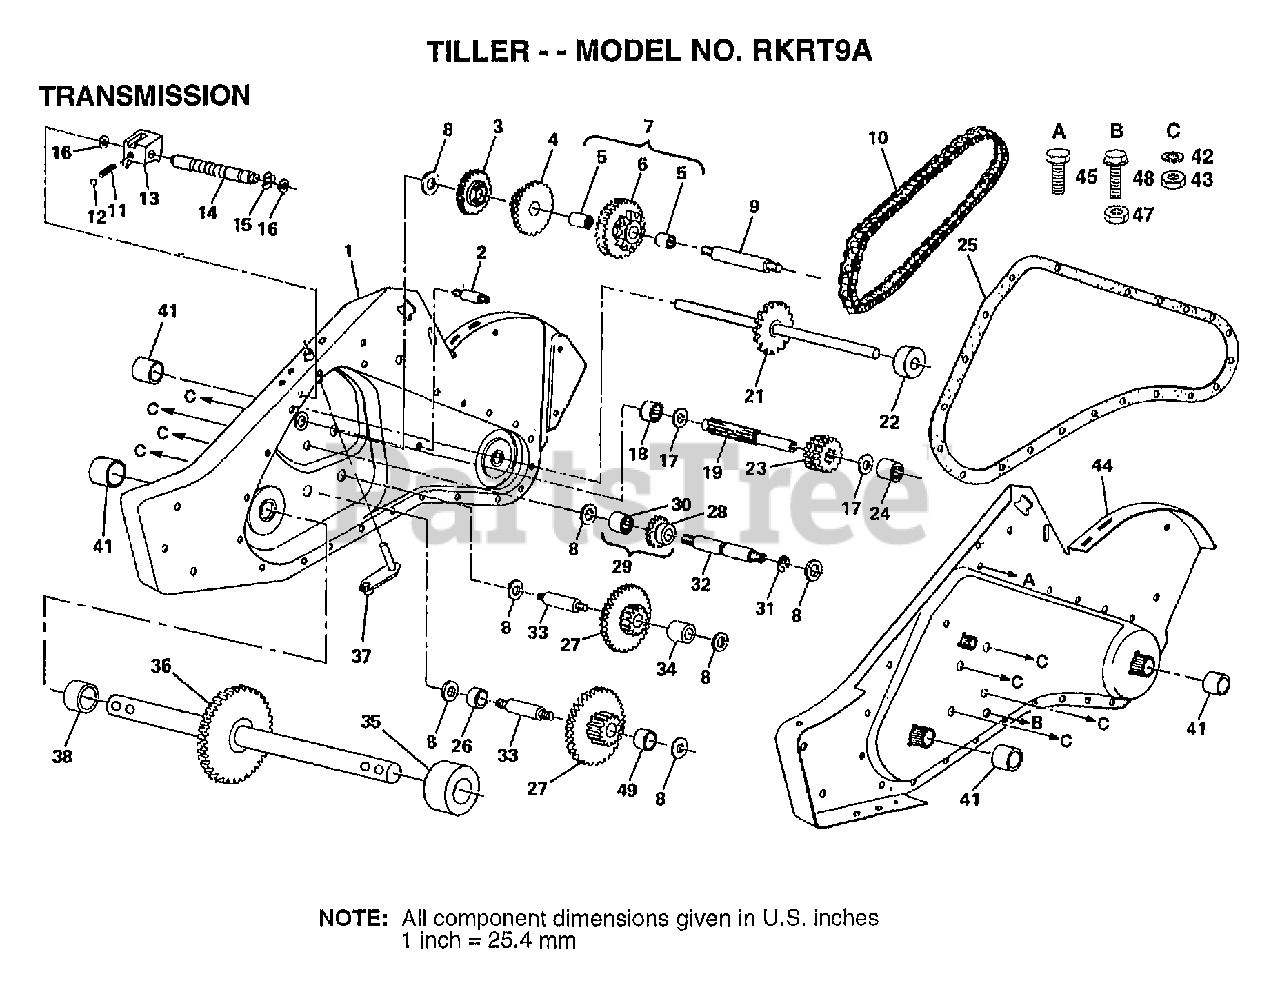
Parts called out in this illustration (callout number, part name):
2	BOLT TI
3	REVERSE GEAR TI
4	CLUSTER GEAR TI
5	"CRT, BEARING"
7	SPROCKET ASSY TI
8	WASHER
9	REDUCTION SHFT TI
10	CHAIN TI
11	SPRING-SHIFT CRT
13	SHIFT FORK TI
14	SHIFT SHAFT TI
15	KLIP RING
16	WASHER SEAL
17	"T, BEARING"
18	"TI, BEARING"
19	SHAFT INPUT
21	SHAFT TINE CRT
22	SPACER CRT
23	INPUT PINION TI
24	NEEDLE BRNG LT
25	GASKET.GEARCASE
26	SPACER CRT
27	GEAR CLUSTER CRT
28	REVERSE GEAR TI
29	GEAR ASSY TI
30	NEEDLE BEARING TI
31	KLIP RING
32	REVERSE SHAFT TI
33	SHAFT CRT
34	SPACER CRT
35	SPACER CRT
36	SHAFT ASSY CRT
37	BRACKET ASM SHIFT
38	SPACER CRT
41	SEAL ASM-OIL
42	LOCKWASHER
43	NUT.ASF.HEX.7/16
44	"GEARCASE ASSY,LH"
45	SCREW 5/16-18X5/8
47	NUT.HEX.5/16-18
48	BOLT TI
49	SPACER CRT
